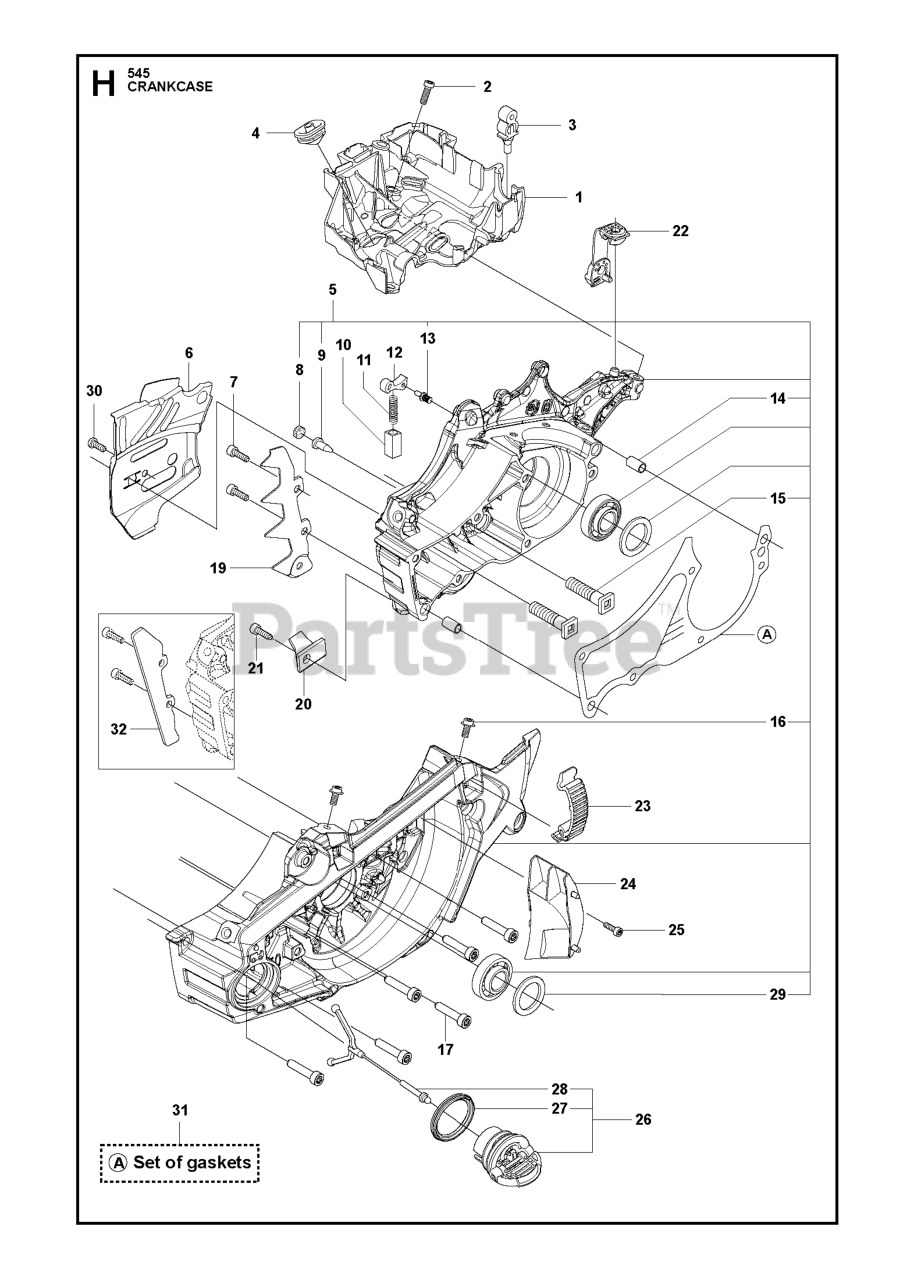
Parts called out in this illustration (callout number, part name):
1	CARBURETTOR AREA BASE
2	SCREW ITXSCFM
5	CRANKCASE ASSY
6	CHAIN GUIDE PLATE
7	SCREW ITXPANM M5X16 T27 10.9
8	PLUG
9	VALVE-CHECK (DUCKBILL)
11	LOCK SPRING
16	SCREW ITXSCM WASHER M5X12 T27
17	SCREW ITXSCM M5X25 12.9 TBO T
20	CHAIN CATCHER
22	DEFLECTION LIMITER
23	BUCKLE ORANGE
24	AIR NOZZLE
25	SCREW ITXSCM M4X15 T27 12.9 T
26	TANK CAP ASSY
27	GASKET TANK CAP
29	RADIAL SEAL
30	SCREW CITXPANT
31	GASKET KIT 50CC
32	BUMPER, BAG
